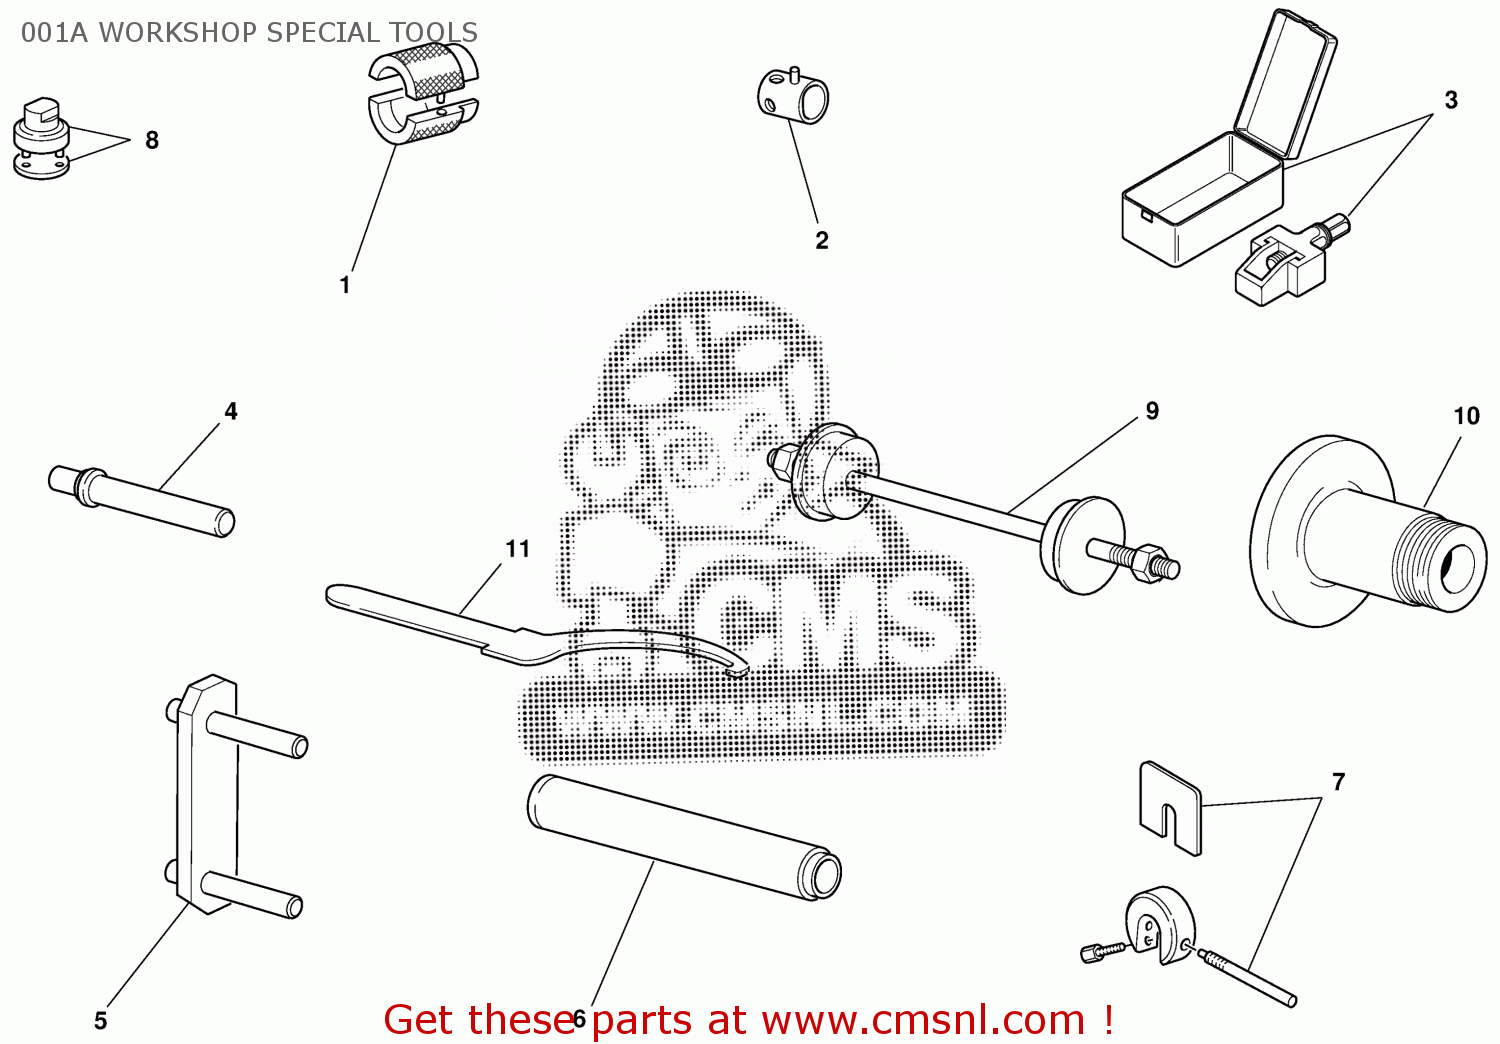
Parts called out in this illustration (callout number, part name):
1	TOOL TO OVERHAUL FORKS
2	WRENCH FOR FRONT WHEEL SPINDLE
3	TOOL FOR ASSEMBLING CHAIN
4	STOPPER ASSEMBLING ROLLER BEARING
5	FRAME/MOTOR SUPPORT
6	DRIVING STOPPER FOR THE HALF BEARING
7	TOOL TO KEEP THE SPACER SHOWA FORKS
8	SPANNER TO ASSEMBLE THE STEERING SLEEVE
9	TOOL ASSEMBLING STEERING TUBE BEARING
10	TOOL BALANCING REAR WHEEL
11	SPANNER FOR ADJUSTING THE ECCENTRIC HUB
